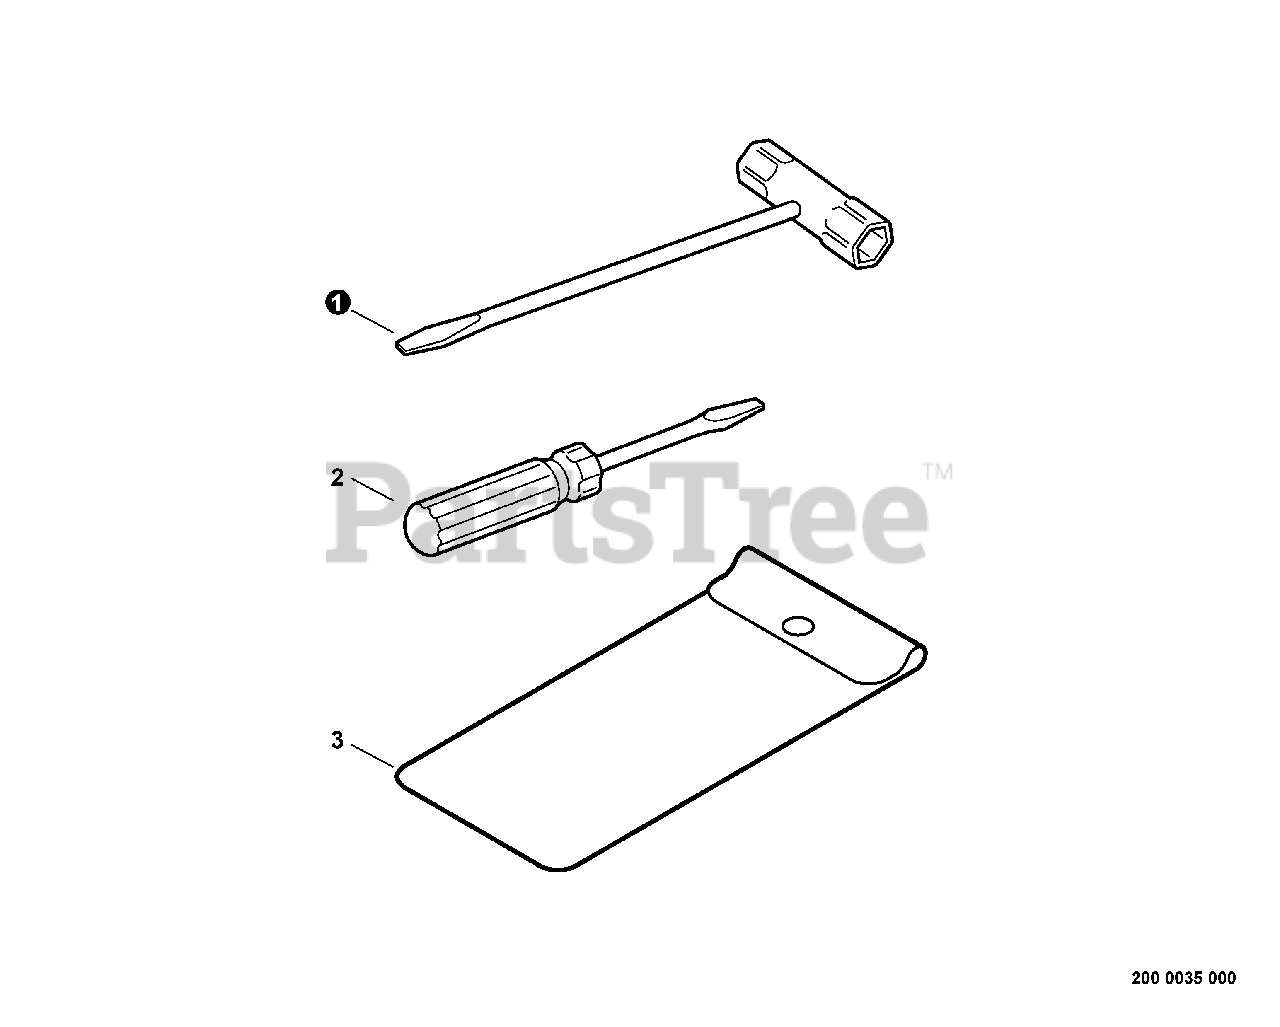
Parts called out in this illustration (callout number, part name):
1	T-WRENCH 13×19 L= 180
2	SCREWDRIVER, SLOTTED
3	BAG, TOOL
